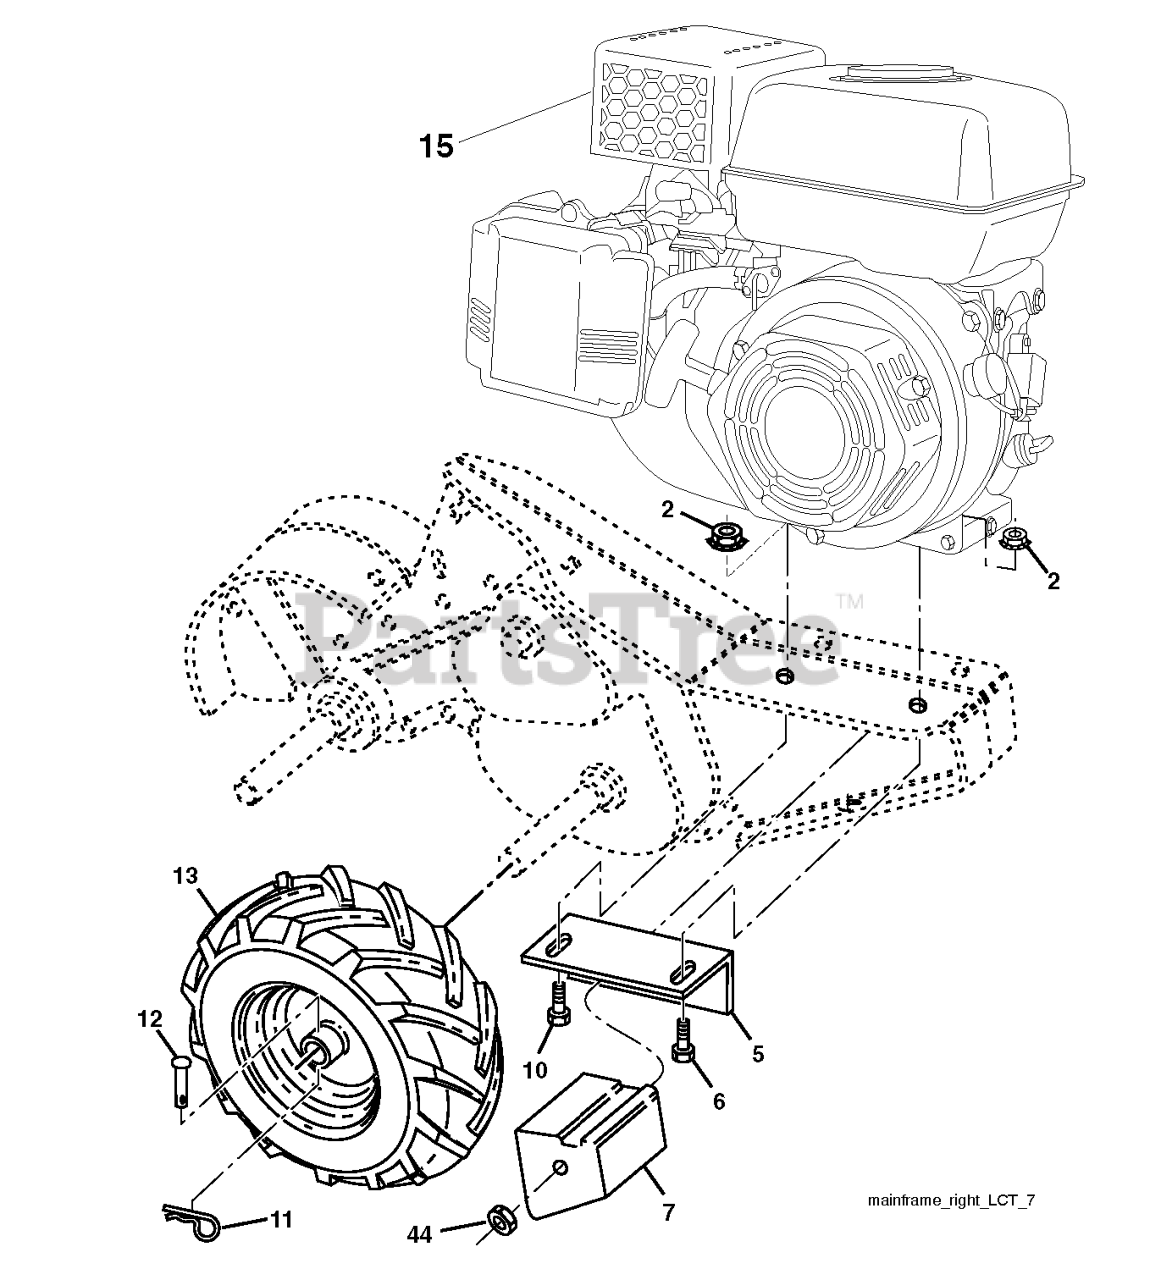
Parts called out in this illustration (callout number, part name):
2	LOCKNUT-FLANGE 5/16-18
5	BRACKET.REINFORCEMENT.RH.BLACK
6	BOLT, HEX 5/16-18X1-3/4
7	COUNTERWEIGHT.RH
10	BOLT
11	RETAINER M
12	RIVET
13	WHEEL 16X4X8.DR TILLER RH.417
15	ENGINE LCT, 208CC, TILLER
